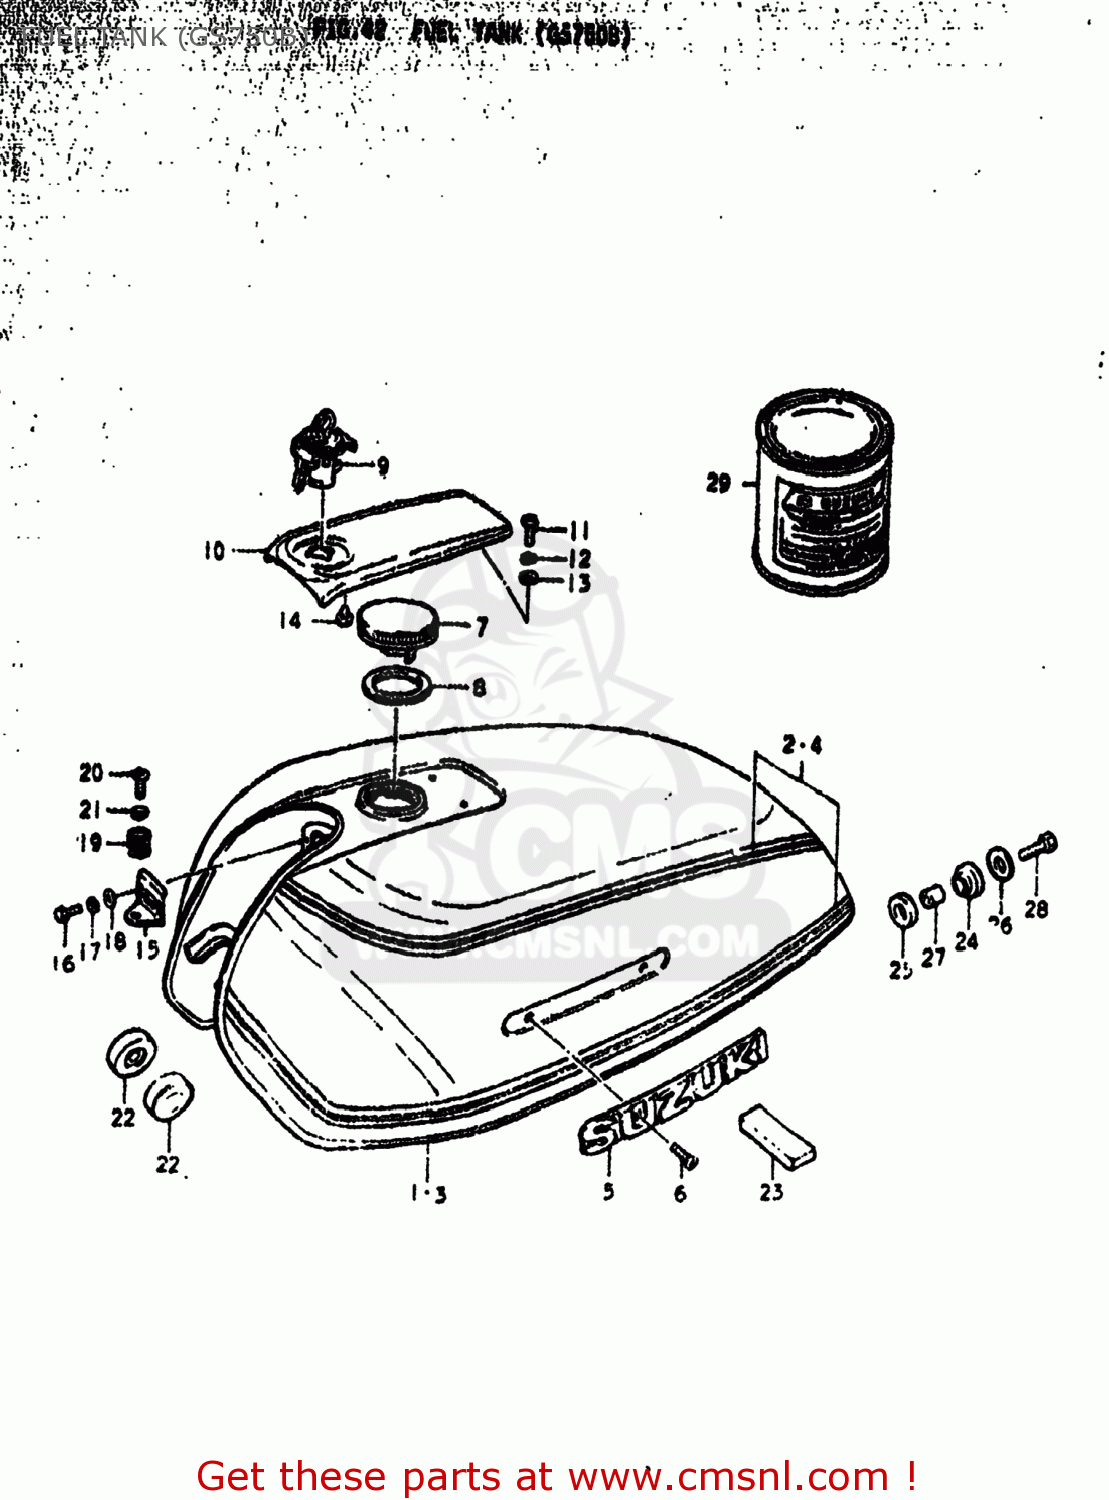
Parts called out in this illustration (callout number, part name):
1	TANK ASSEMBLY,FUEL
2	TAPE SET,FUEL TANK STRIPE
3	TANK ASSEMBLY,FUEL
4	TAPE SET,FUEL TANK STRIPE
5	EMBLEM,FUEL TANK
6	SCREW
7	CAP,FUEL TANK
8	GASKET (NAS)
9	LOCK,FUEL TANK FR COVER
10	COVER,FUEL TANK
11	BOLT
12	LOCK WASHER
13	WASHER
14	CUSHION
15	HOLDER,FUEL TANK FRONT COVER
16	BOLT
17	LOCK WASHER
18	WASHER
19	SPRING
20	SCREW
21	LOCK WASHER
22	CUSHION
23	CUSHION
24	CUSHION
25	CUSHION
26	WASHER (8.5X29X1.6)
27	SPACER (8.2X12X17)
28	BOLT (8X30)
29	PAINT,BLACK
